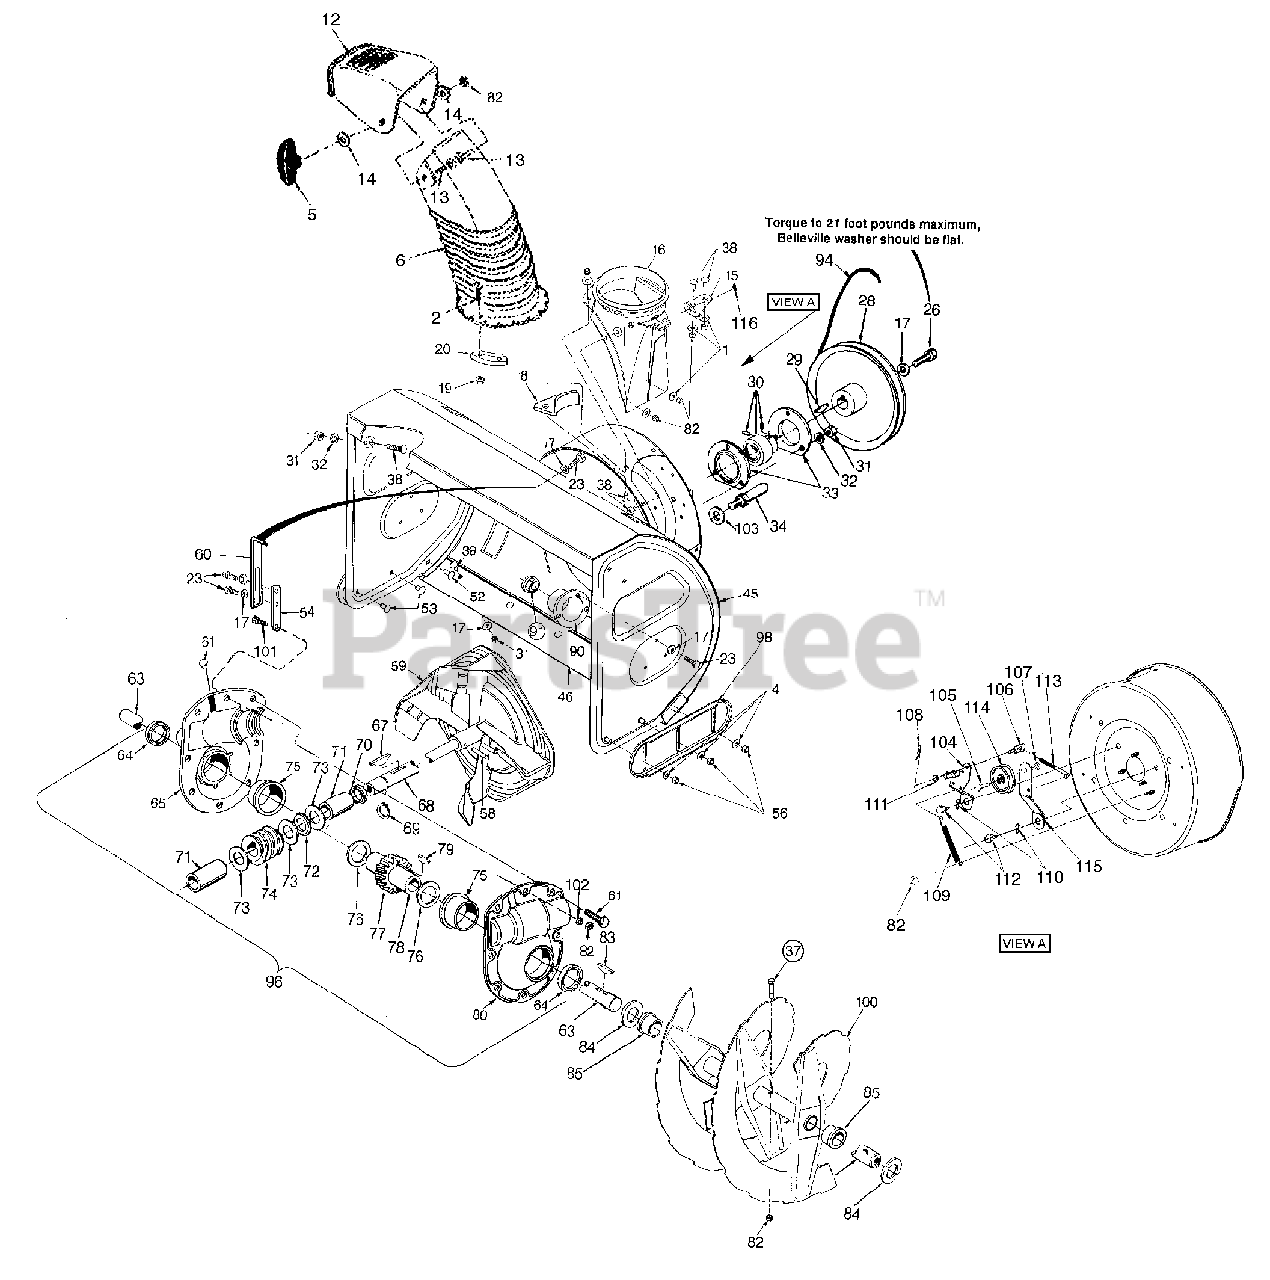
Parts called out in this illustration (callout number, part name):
1	Flat Washer .344 ID x .875 OD
2	Truss. Hd. Mach. Scr. 1/4-20 x .75
4	Belleville washer
6	6" Lower Chute Remote Tilt
16	Chute Adapter
17	Bell. Washer .345 ID x .88 OD x .06
19	Hex Cent. L-Nut 1/4-20 w/ Flange
20	Chute Flange Keeper
23	Hex Wash HD Self-Tap Scr 5/16-18 x .75
26	Hex Screw 5/16-18 x .75
28	1/2" V-Pulley .875 ID x 10.12 OD
29	#9 Hi-Pro Key 3/16 x 3/4 Dia HT
30	Self-Aligning Bearing .875 ID
31	Hex Nut 5/16-18 GD. 5
32	L-Wash 5/16 ID
33	Bearing Housing
34	Belt Keeper Studs 3/8-16 x 2.75
38	Carriage Bolt 5/16-18 x .75
52	Carriage Bolt 3/8-16 x 1.00 Gr. 5
53	Carriage Bolt 3/8-16 x .75" Lg.
56	Hex Jam Nut 3/8-16
58	Spring Spiral Pin Heavy 5/16 dia x 1.7
63	Spiral Axle -33"
64	Oil Seal 1.50 ID Garlock (76 x 6223)
65	Gear Housing Half - RH
67	#9 Hi-Pro Key 3/16 x 3/4 dia HT
68	Auger Drive Shaft
69	Snap Ring for .875 dia. shaft
70	Oil Seal for .875 ID (76 x 6133)
71	Sleeve Bearing .875 ID
72	Thrust Bearing .88 ID x 1.44 OD x .078
73	Flat Washer .88 ID x 1.4 OD x .125
74	Worm Gear LH Double Thread
75	Flange Brg. 1.5 ID x 1.75 OD x .80
76	Flat Washer 1.5 ID x 2.0 OD x .03
77	Worm Gear LH Double Thread (Bronze)
78	Worm Gear Shaft
79	#91 Woodruff Key 1/4 x 3/4 dia
80	Gear Housing Half LH
81	Hex Flange Scr. 5/16-18 x .75
82	Hex Ins. L-Nut 5/16-18
83	#91 Woodruff Key 1/4 x 3/4 dia
85	Flange Bearing
91	Flange Bearing w/flats
94	V-Belt 1/2 x 44 LG
96	Worm Gear Box Ass'y
102	5/16 Sprg Wash
103	3/8 Sprg Lock Wash
104	Brkt Ass'y Brkt
105	Scr Hex Cap 3/8-24 x 1.5 GRD 5
106	Adjustment Ferrule
107	Hex Ins L-Nut 3/8-24
108	Intern Cot-Pin 5/16 dia
109	Spr Extn .470 dia x 4.75 Lg
110	Wave Washer .66 ID x .88 OD
111	Fl-Wash SAE .34 x .68
112	Shld Scr .625 dia x .170 x .062
113	Rod Idler Auger
114	3.0 OD Flat Idler with Flanges
116	Plastic Bushing .380 ID
